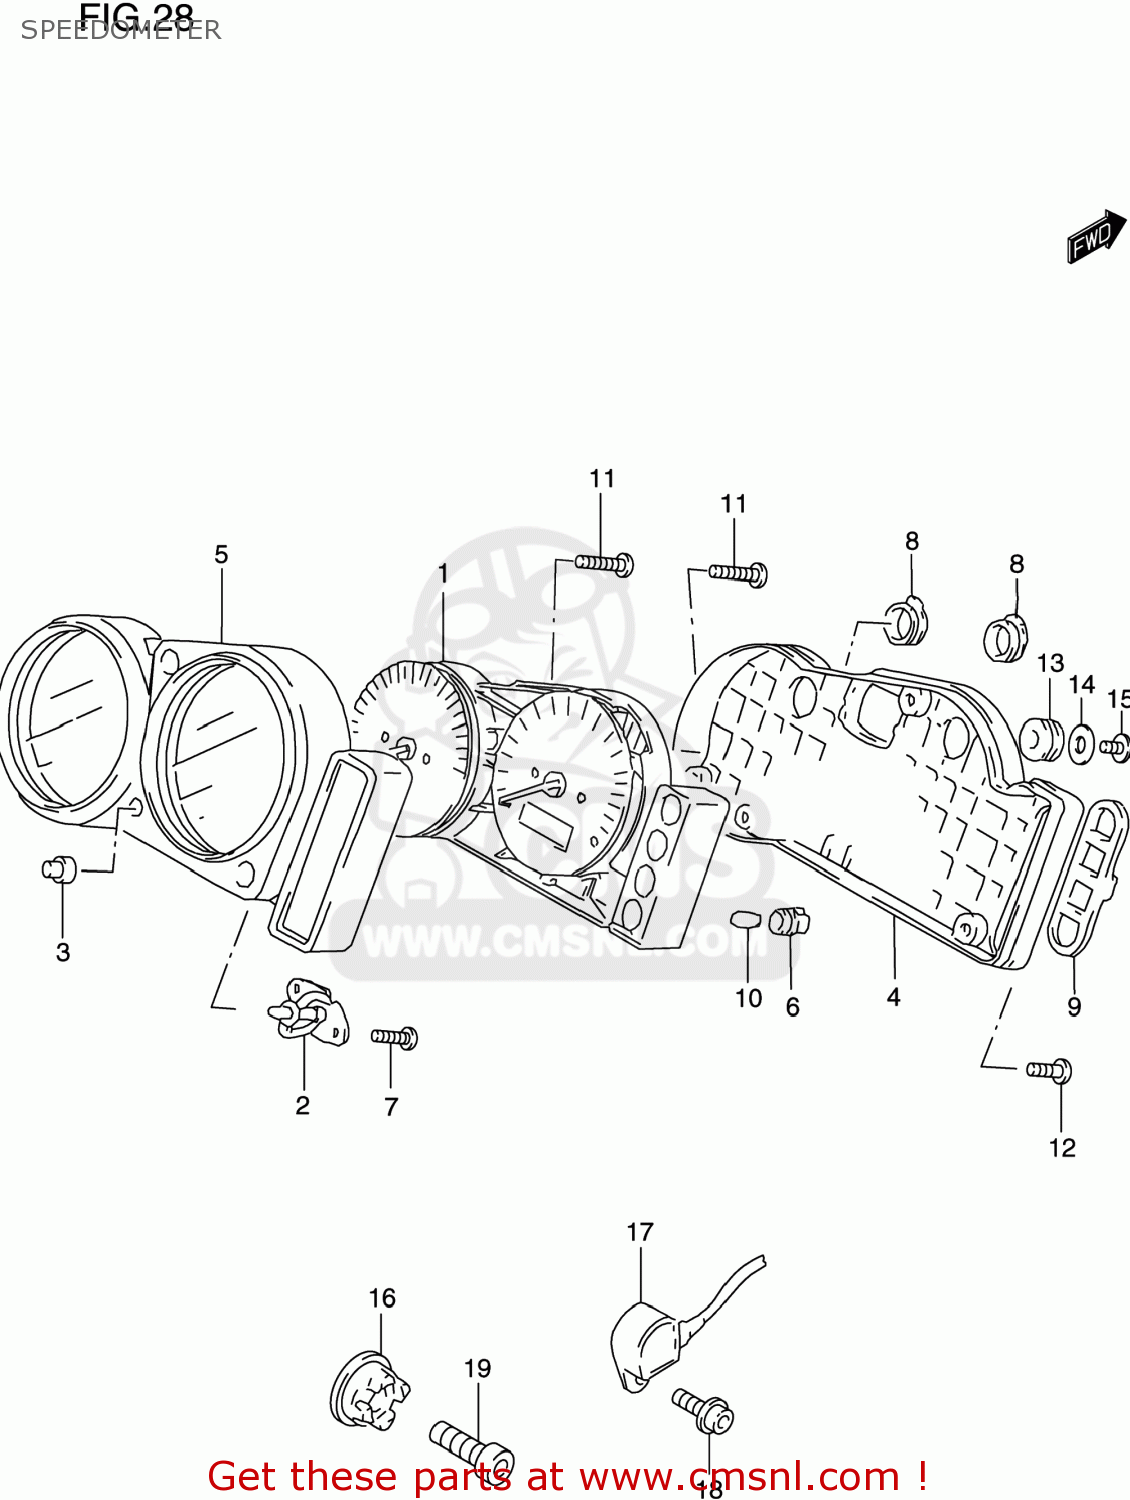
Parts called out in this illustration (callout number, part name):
1	SPEEDOMETER & TACHOMETER ASSEMBLY
2	ATTACHMENT,SWITCH
3	SWITCH,GUM
4	CASE ASSY
5	VISOR
6	SOCKET(T:6.5)
7	SCREW(3X10)
8	CAP,BLIND NO.1
9	CAP,BLIND NO.2
10	BULB(12V1.7W,T6.5)
11	SCREW
12	SCREW
13	CUSHION,METER
14	WASHER(5.5X16X1.2)
15	SCREW
16	ROTOR,SPEED
17	SENSOR,SPEED
18	BOLT
19	BOLT
